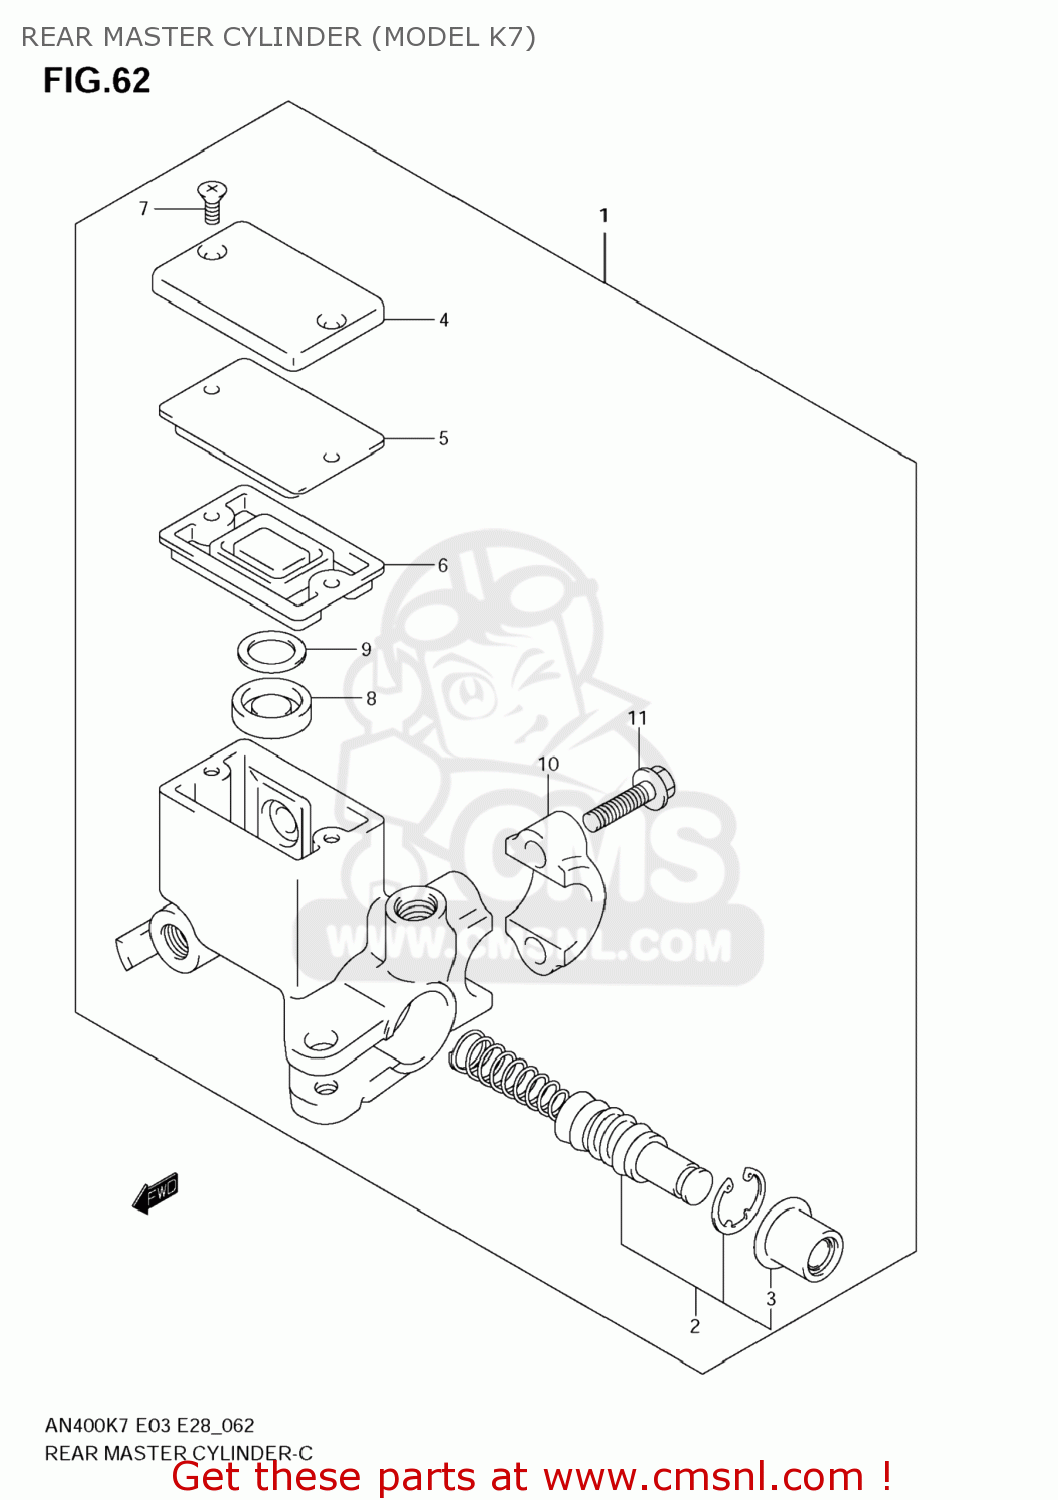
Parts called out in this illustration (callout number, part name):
1	CYLINDER ASSY,RR MASTER
2	PISTON/CUP SET
3	BOOT
4	CAP
5	PLATE,DIAPHRAGM
6	DIAPHRAGM
7	SCREW
8	SEPERATOR
9	PLATE
10	HOLDER
11	BOLT(6X22)
